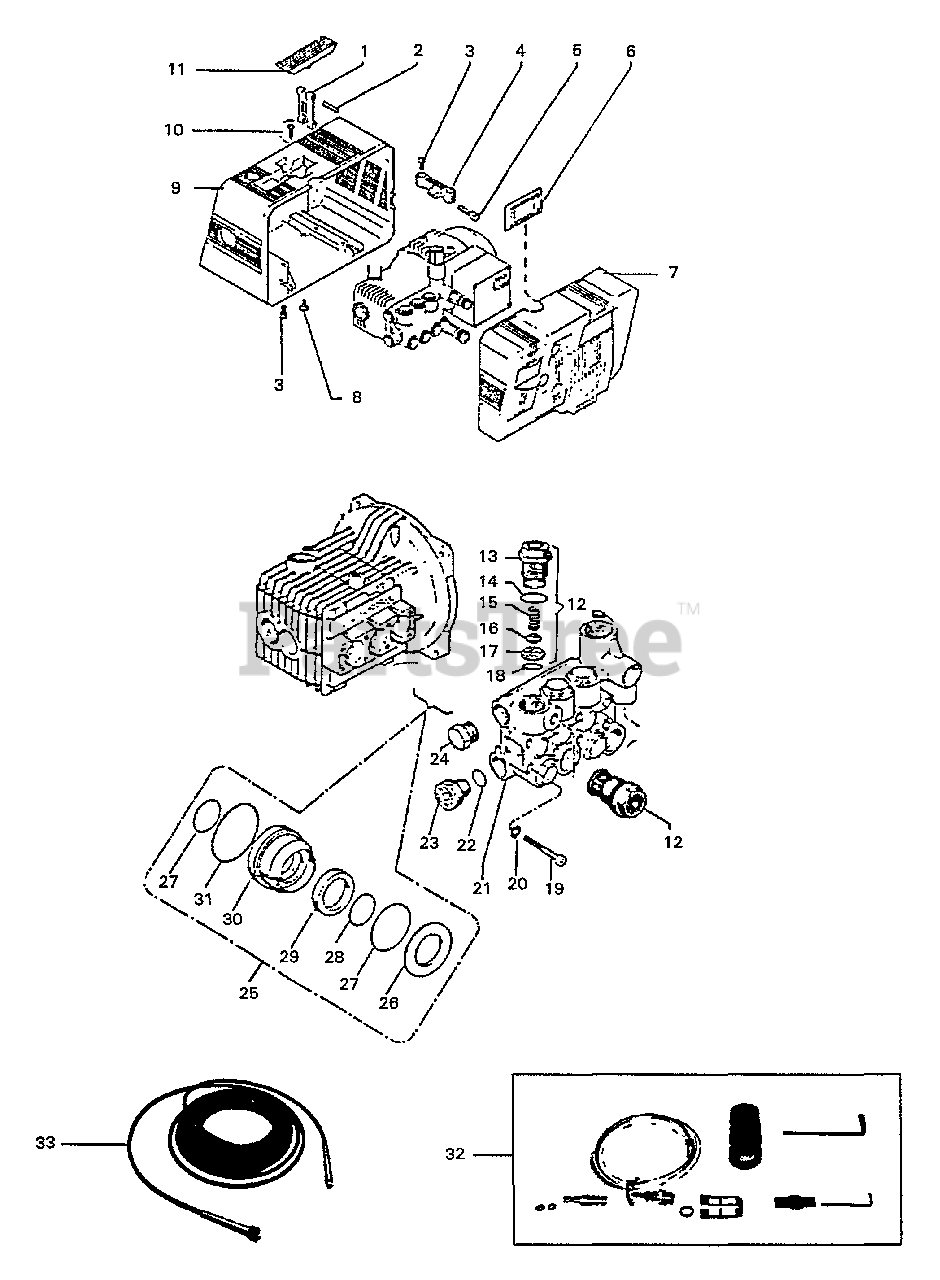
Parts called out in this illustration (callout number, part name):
1	ARM, HANDLE
2	PIN
3	SCREW M8×16
4	PLATE, HANDLE RETAINER
5	SHAFT
6	PLATE, ON-OFF
7	COVER, FRONT
8	PLUG
9	COVER - REAR
10	SCREW - 4×13
11	HANDLE
12	VALVE KIT
13	CAP, VALVE
14	O-RING
15	SPRING, VALVE
16	PLATE
17	SEAT, VALVE
19	SCREW M6×40
20	LOCKWASHER - 6
21	MANIFOLD
22	O-RING
23	PLUG
24	CAP
25	RETAINER REBUILD PACKING KIT
26	WASHER
27	O-RING
28	O-RING
29	PACKING
31	O-RING
32	ACCESSORY KIT
33	HOSE - 8M
